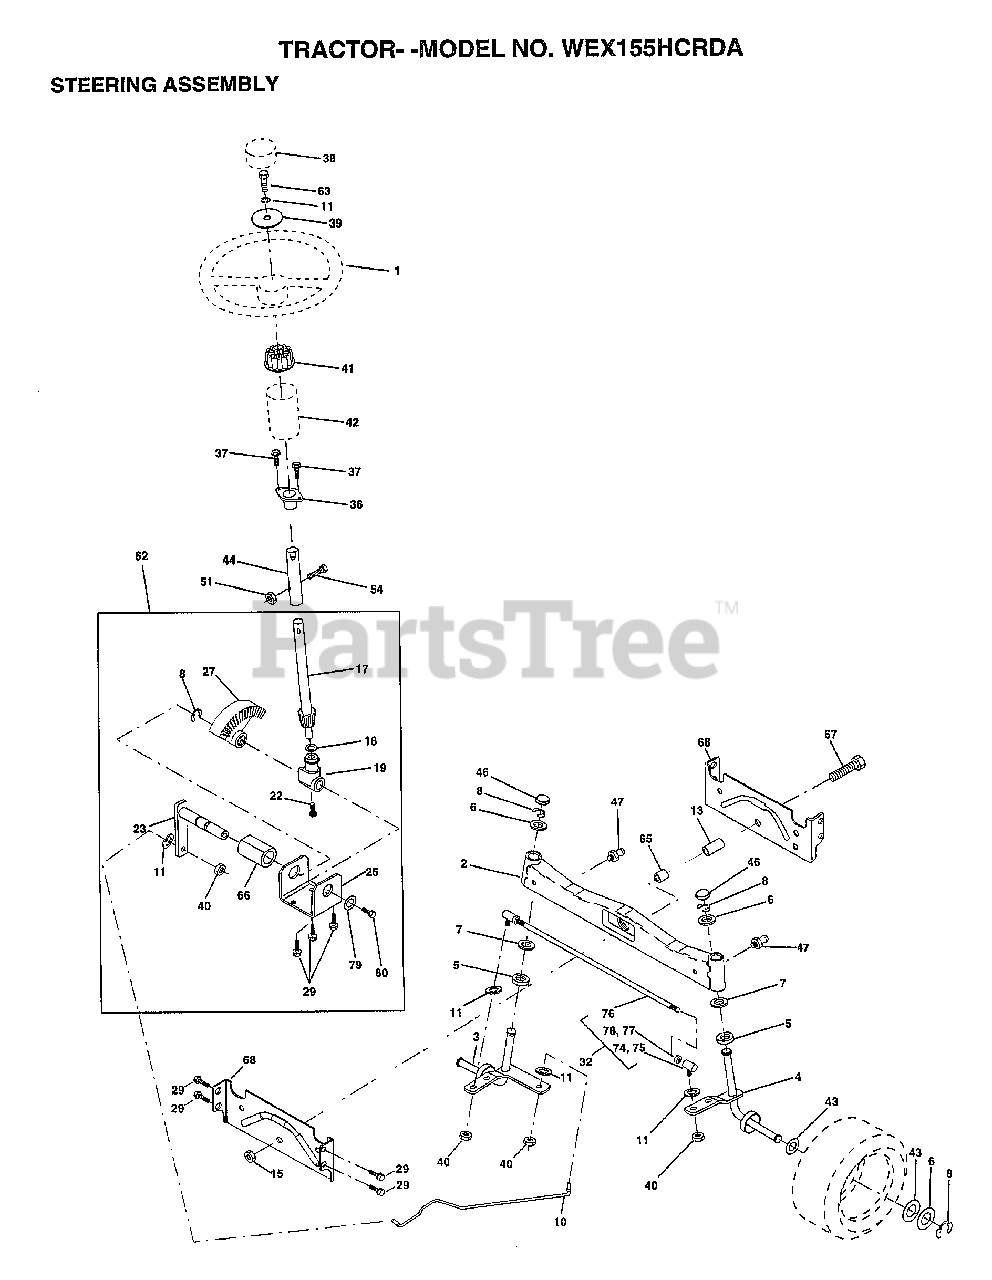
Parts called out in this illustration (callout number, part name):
1	WHEEL STR AYP BLK
3	"SPINDLE ASM,LH"
4	"SPINDLE ASM,RH"
5	WASHER .T
6	WASHER
7	WASHER
8	RING
10	LINK.DRAG
11	LOCKWASHER
13	BEARING.FRT.SPACER.AXLE
15	"NUT-LOC,FLANGE LT"
17	SHAFT ASM STEERIN
18	THRUST WASHER
19	SUPPORT.SHAFT.STEER
22	SCREW.HX.WSH.HD
23	SHAFT.ASM.PITMAN
25	BRKT-STEERING
27	GEAR SECTOR
29	SCREW
32	ROD.ASM.TIE.BALL
36	BUSHING.STEERING
37	"SCREW-TT,10-32 FL"
38	CAP STEER AYP
39	WASHER T
40	GRIPCO NUT
41	ADAPTER LT
42	BOOT.STEER.PL
43	WASHER
44	EXT SHAFT STEERIN
46	CAP
47	ZERK M
51	NUT
54	BOLT
62	KIT.STEER.ASM
63	BOLT
65	SPACER AXLE
66	"BEARING-ARM,PITMA"
67	BOLT
68	BRACE AXLE
74	JOINT.RH
75	JOINT.LH
77	NUT
78	NUT
79	WASHER
80	BOLT.HX.NYLON3/8-16X3/
81	SCREW.HXWSH.3/8
